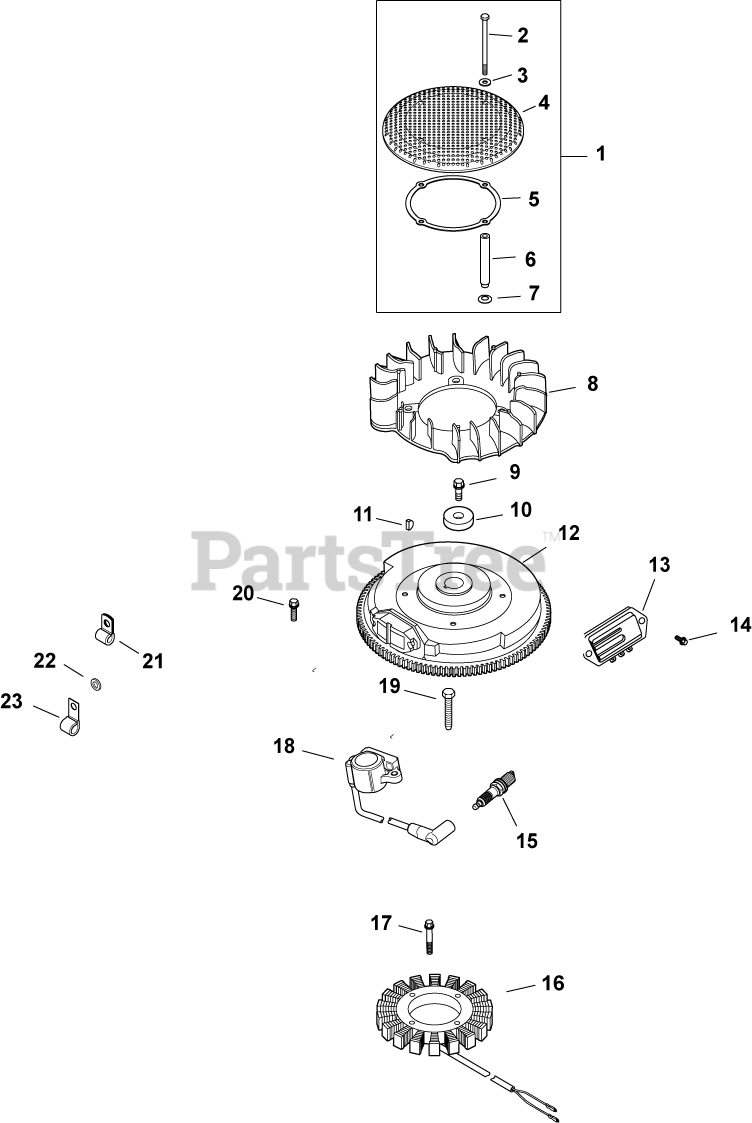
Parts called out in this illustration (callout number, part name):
1	KIT, CHOPPER SCREEN
2	SCREW, CAP M6X1.0X99.5
3	WASHER, FLAT 1/4" (O.D. 5/8")
4	SCREEN, GRASS-USE 24 162 39-S
5	RING, SUPPORT USE 25 141 08-S
7	WASHER, SPRING 10 MM
8	FAN USE 24 755 253-S
9	SCREW, FLG M10X1.5X45 - (#25086361S)
10	WASHER, FLAT 13/32"
11	KEY, 3/16" X 5/8"
12	FLYWHEEL ASSEMBLY (LW)-USE 24 025 58-S
13	REG/RECT-15 AMP (KM)-USE 41 403 10-S
14	SCREW, HEX FLANGE HI-LO
15	PLUG, SPARK (STD)
16	KIT, 15 / 20 AMP STATOR
17	SCREW, SKT SET #10-24X1/4"
18	MODULE, SPARK ADV -USE 24 584 89-S
19	SCREW, M5X0.8X25 - (#25086402S)
20	SCREW, FLG THD FRM M5X.8X20-(#25086399S)
21	CLIP, CABLE
22	WASHER, FLAT 1/4" (O.D. 1/2")
23	CLIP, TUBE & WIRING (KM)
